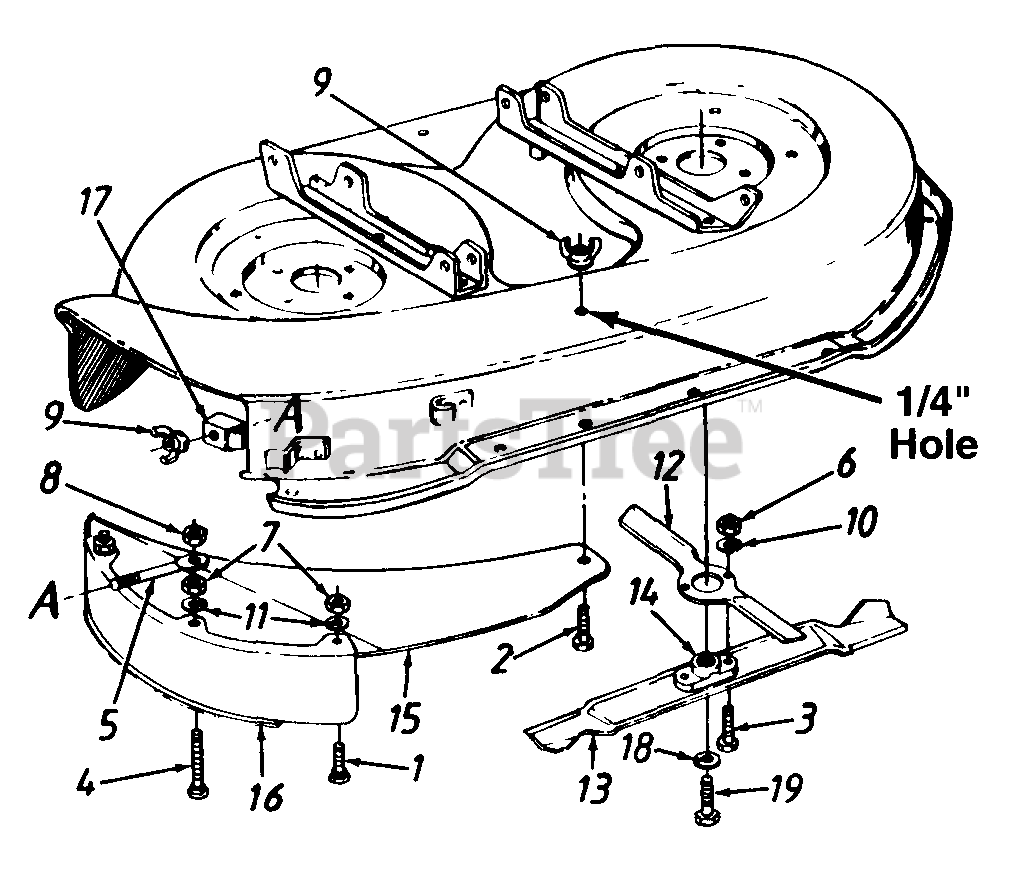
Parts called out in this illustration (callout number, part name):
1	Carriage Bolt 1/4-20 x .62" Lg.
2	Hex Bolt 1/4-20 x 1" Lg.
3	Hex Bolt 7/16-20 x 1.25" Lg. (Gr. 5)
4	Carriage Bolt 1/4-20 x 1" Lg.
5	Retaining Bolt
6	Hex Nut 7/16-20 Thd
7	Hex Nut 1/4-20 Thd
8	Hex L-Nut 1/4-20 Thd.
9	Wing Nut
10	L-Wash. 7/16" I.D.
11	L-Wash. 1/4" I.D.
12	Mulching Blade 12.5"
13	Mulching Blade 19.38"
14	Blade Adapter
18	L-Wash. 3/8" I.D.
19	Hex Bolt 3/8-24 x 1" Lg (Gr. 8)
